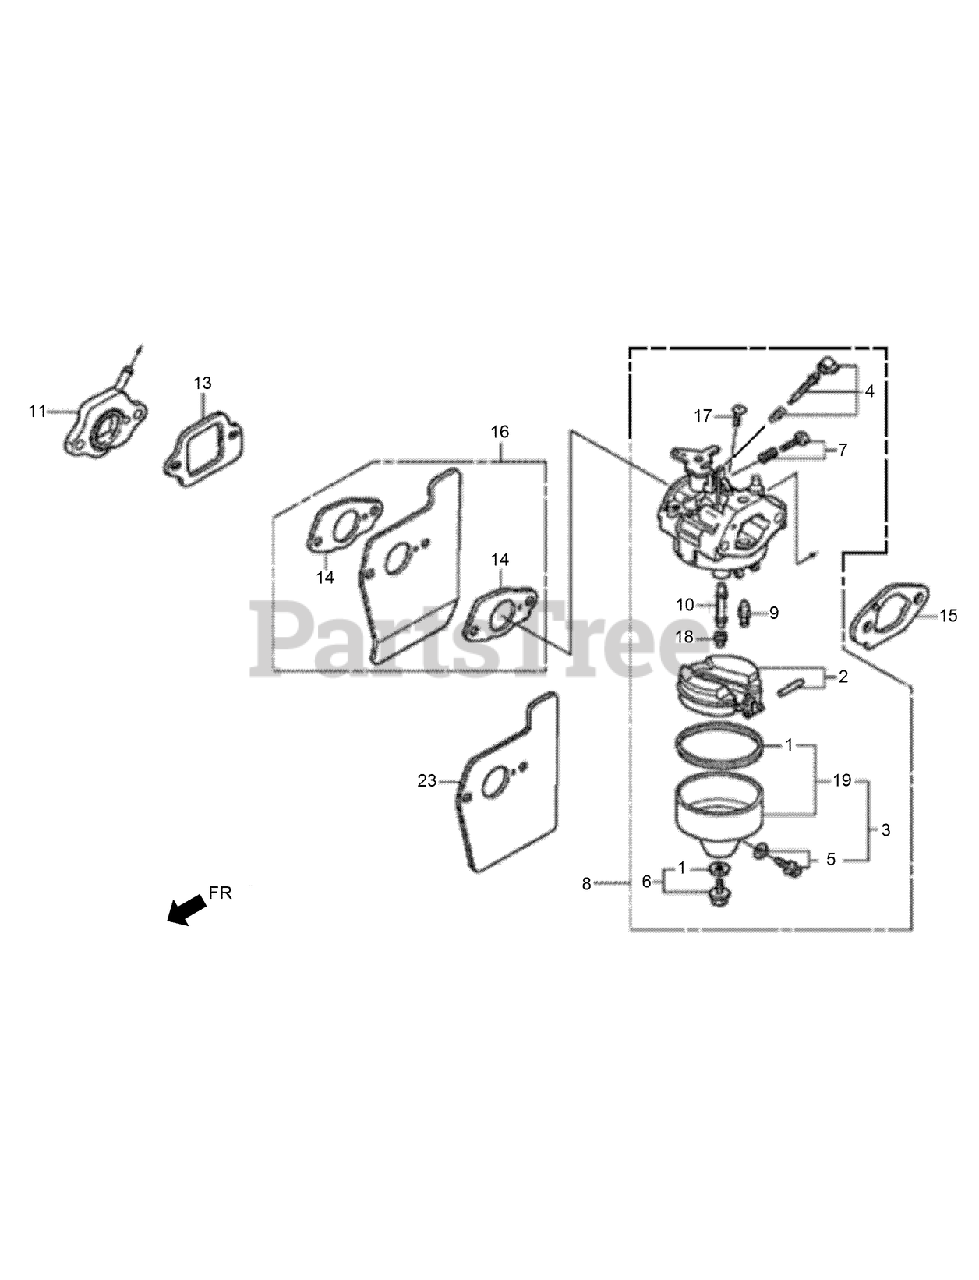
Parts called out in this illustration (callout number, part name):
1	PACKING SET
2	FLOAT SET
3	CHAMBER SET-FLOAT
4	SCREW SET
5	SCREW SET-DRAIN
6	SCREW SET
7	SCREW SET
8	CARBURETOR ASM (to S/N 2017060)
8	CARBURETOR ASM
9	VALVE-FLOAT
10	NOZZLE-MAIN
11	CARBURETOR INSULATOR ASM
13	PACKING-INSULATOR
14	PACKING-CARBURETOR
15	PACKING-CARBURETOR
16	AIR GUIDE ASM
17	SCREW-PAN-5X6
18	JET-MAIN NO. 62
19	CHAMBER SET-FLOAT
23	GUIDE-AIR
